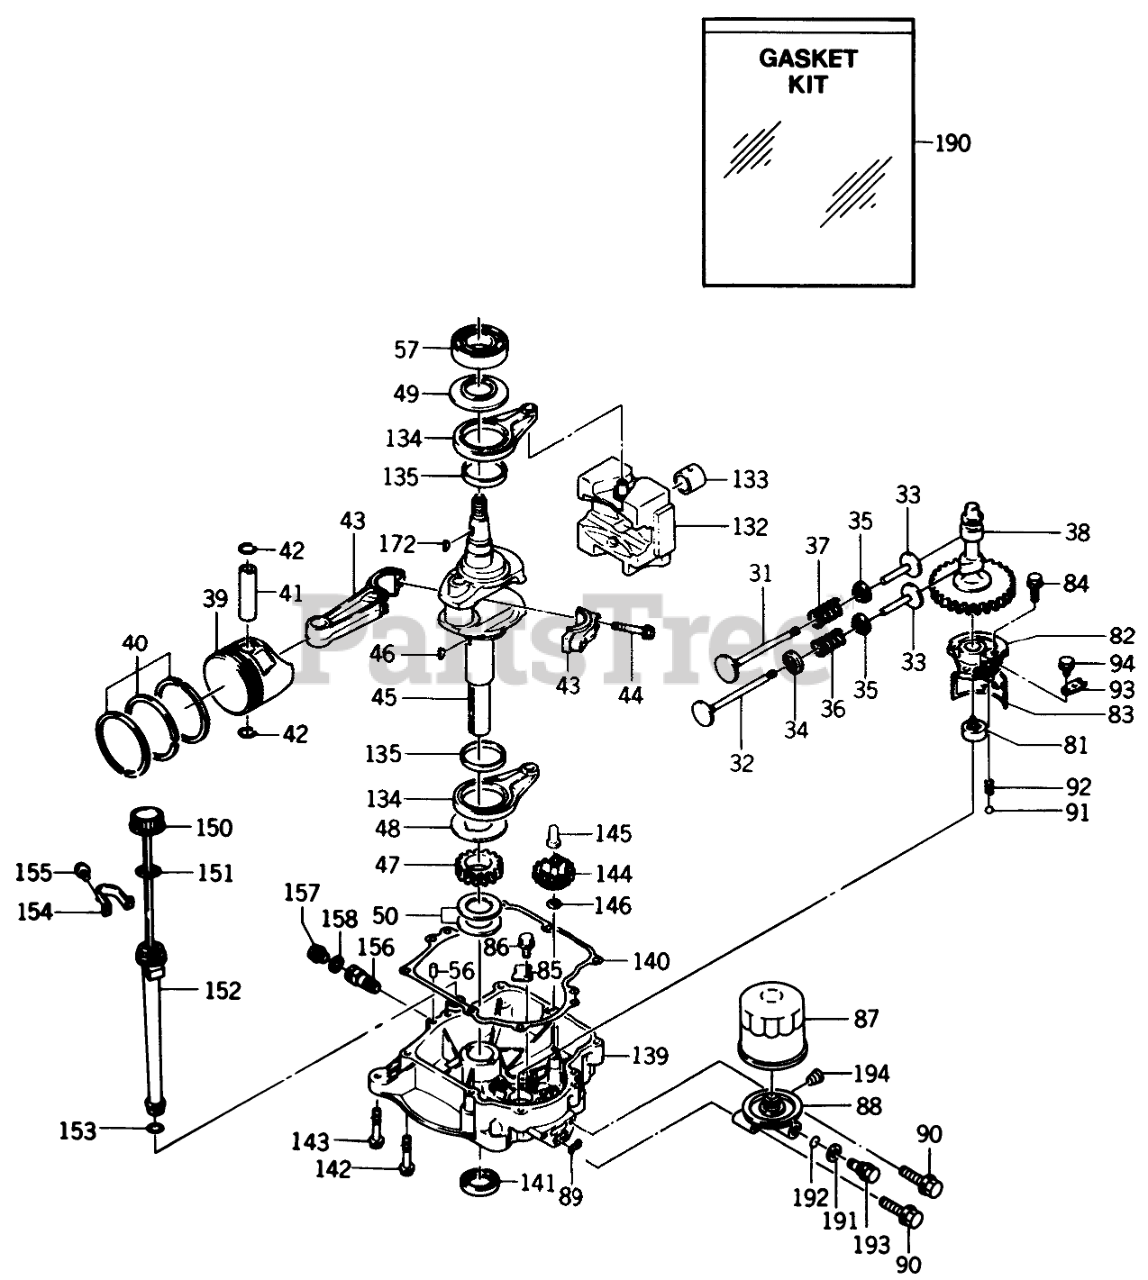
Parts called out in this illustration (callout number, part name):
31	Intake Valve
32	Exhaust Valve
35	Retainer-Spring
36	Spring-Valve
37	Spring-Valve
38	Cam Shaft
40	Set-Ring Piston
41	Pin-Piston
42	Ring-Snap
43	Connecting Rod Ass-y-Standard (includes item 44)
45	Crankshaft Complete
47	Gear
50	Shim (1.18)
56	Dowel Pin
57	Ball Bearing
81	Pump ASM-Oil
82	Cover-Pump
83	Filter-Oil
84	Bolt-Flanged (8X25)
86	Bolt 5 x 8
87	Filter
88	Bracket (includes item 194)
90	Bolt 8 x 45
93	Plate
94	BOLT-FLANGED (6X10)
132	Weight Complete (includes item 133)
133	Bushing
134	Rod Assy (includes item 135)
135	Bearing Plane
140	Gasket
142	Bolt-Flanged (8X45)
143	Bolt-Flanged (8X25)
144	Governor ASM
145	Sleeve
151	Gasket
153	O-RING (16mm)
155	Bolt
157	Plug
158	Gasket
172	Key-Woodruff
190	Overhaul Gasket Set
191	Gasket
192	O Ring
